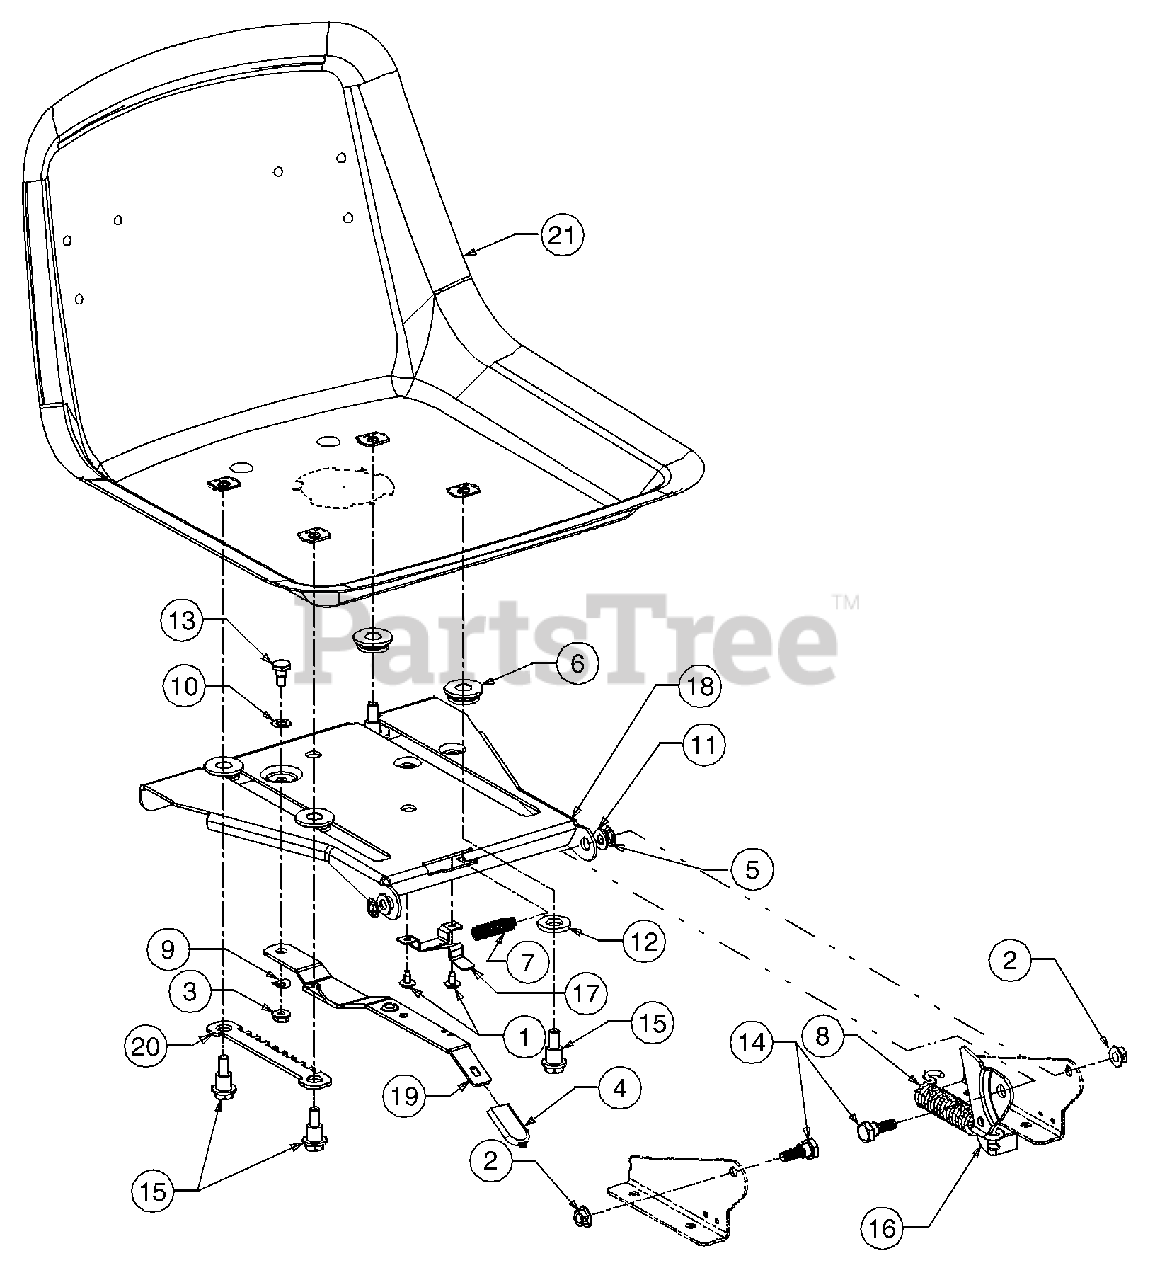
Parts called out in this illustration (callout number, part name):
1	Screw, #10-16, 0.375
2	Nut, Flange Lock, 5/16-18, Gr5
3	Nut, Flange Lock, 1/4-20
4	Grip, Seat, Adjustment (Yellow)
5	Nut, Speed, .3125 ID
6	Spacer, Seat, Adjustment
7	Spring, Compression .41 OD x 1.50
8	Spring, Extension, .84 Dia x 4.6 Lg.
9	Washer, Spring, .265 x .562 x.025
10	Washer, Flat, .344 ID x .62 OD
11	Washer, Flat, .344 x .688 x .065
12	Washer, Flat, .531 x 1.062 x .134
13	Screw, Shoulder, .340 x .285, 1/4-20
14	Shoulder, Screw .437 x .286 Lg
15	Screw, Shoulder, .50 x.50, 5/16-18
16	Bracket, Lift, Seat, L.H.
17	Stop, Seat, Adjustment
20	Selector, Seat, Adjustment
21	Seat, Mid-back, V-1480
